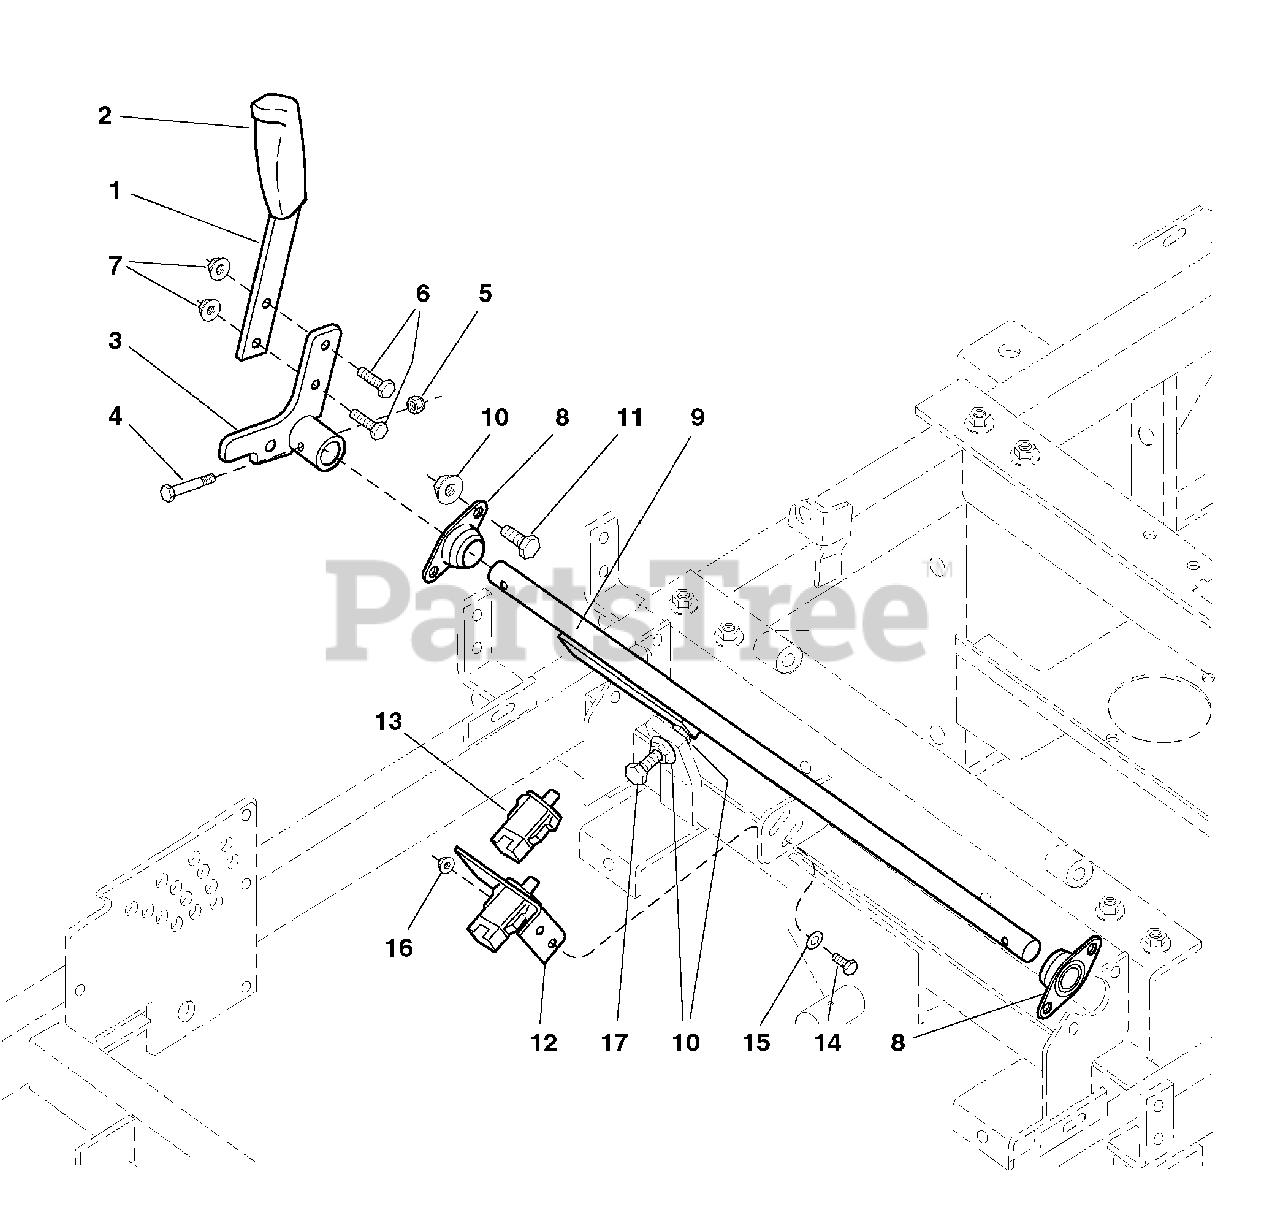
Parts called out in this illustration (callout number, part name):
1	BRAKE HANDLE
3	BRAKE HANDLE MOUNT
4	CAPSCREW, Hex Hd, 1/4-20 x 1-3/4
5	NUT, Hex, Nylon Lock, 1/4-20
6	CAPSCREW, Hex Hd, 5/16-18 x 1
7	NUT, Hex, Serrated Flange, 5/16-18
8	BEARING, Flange
9	BRAKE HANDLE SHAFT
10	NUT, Hex, Serrated Flange, 3/8-16
11	CAPSCREW, Hex Hd, 3/8-16 x 3/4
12	SWITCH MOUNT BRACKET
13	SWITCH (See Electrical Group)
14	CAPSCREW, Hex Hd, 1/4-20 x 3/4
15	WASHER, 1/4 SAE (5025154)
16	NUT, Hex, Serrated Flange, 1/4-20
17	CAPSCREW, Hex Hd, TFL, 3/8-16 x 1-3/4
